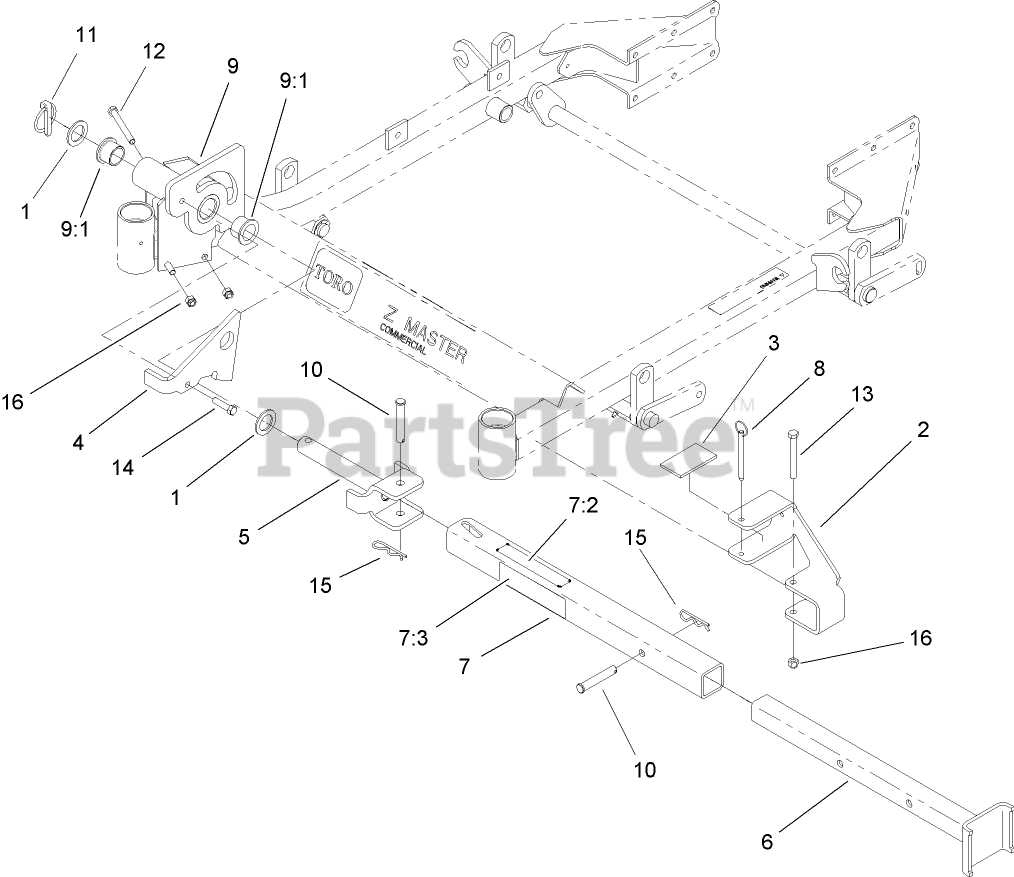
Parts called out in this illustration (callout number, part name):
1	WASHER-THRUST
2	Bracket-Cradle
3	Cushion-Rubber
4	BRACKET-LATCH
5	PIN-PIVOT
6	Inner Leg ASM
7	Leg ASM
7:2	DECAL-Z STAND
7:3	DECAL-WARNING
8	PIN-HITCH, COTTERLESS
9	STAND ASM
9:1	BUSHING
10	PIN-CLEVIS
11	PIN-LYNCH
12	SCREW-HH
13	SCREW-HH
14	SCREW-HH
15	PIN-HAIR
16	NUT-LOCK, NI
